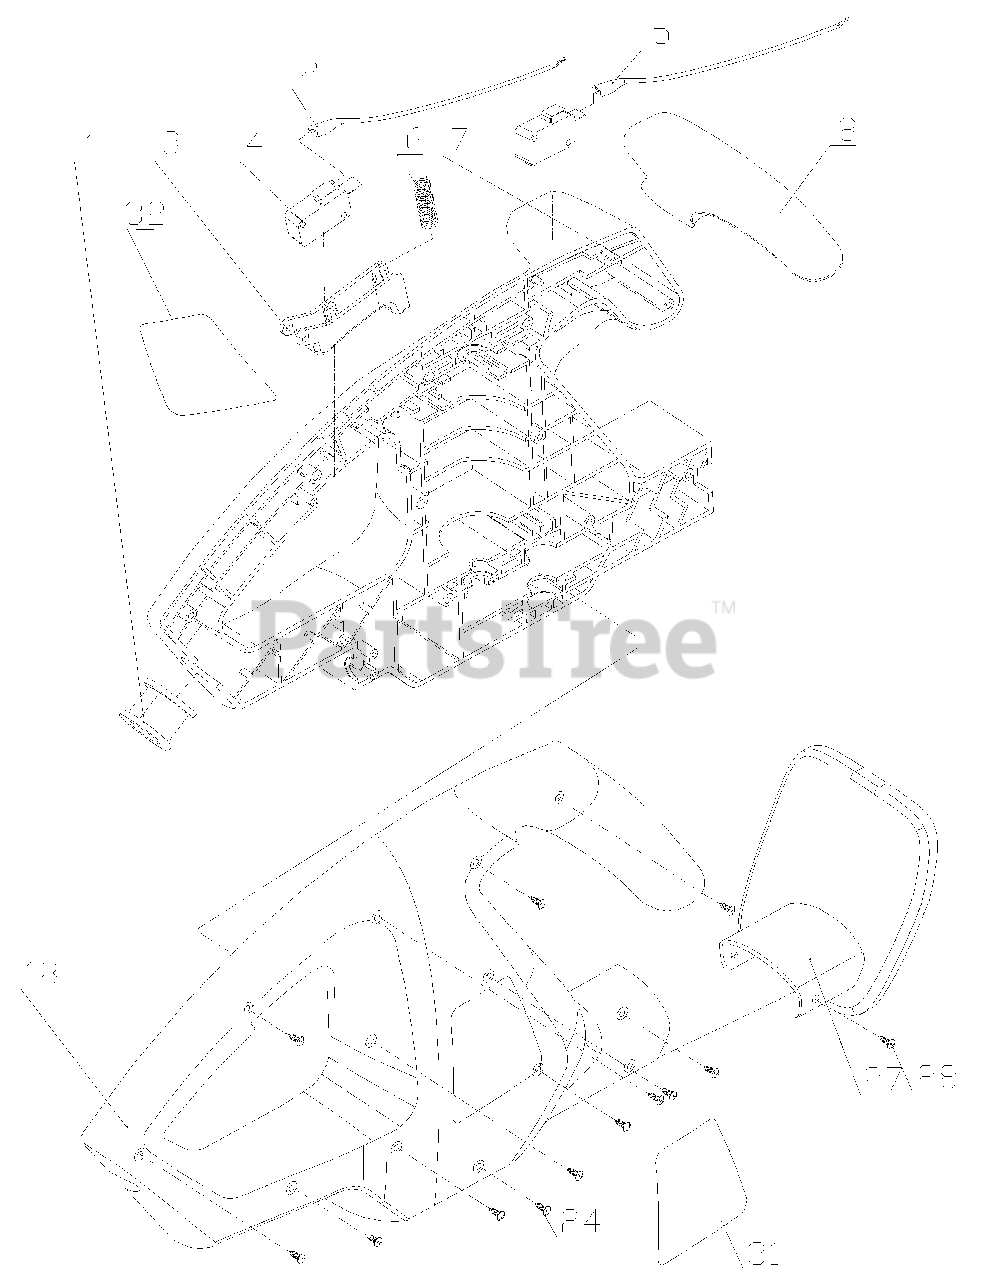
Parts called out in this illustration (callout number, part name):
7	HOUSING (L)
9	FIELD ASS'Y
12	18" BLADE
14	ECCENTRIC SHAFT
15	OUTPUT SHAFT
17	BRUSH HOLDER
18	HOUSING (R)
19	TERMINAL BLOCK
21	STRAIN RELIEF
22	CORD GUARD
23	POWER CORD
25	BLADE COVER
31	LABEL (R)
32	LABEL (L)
